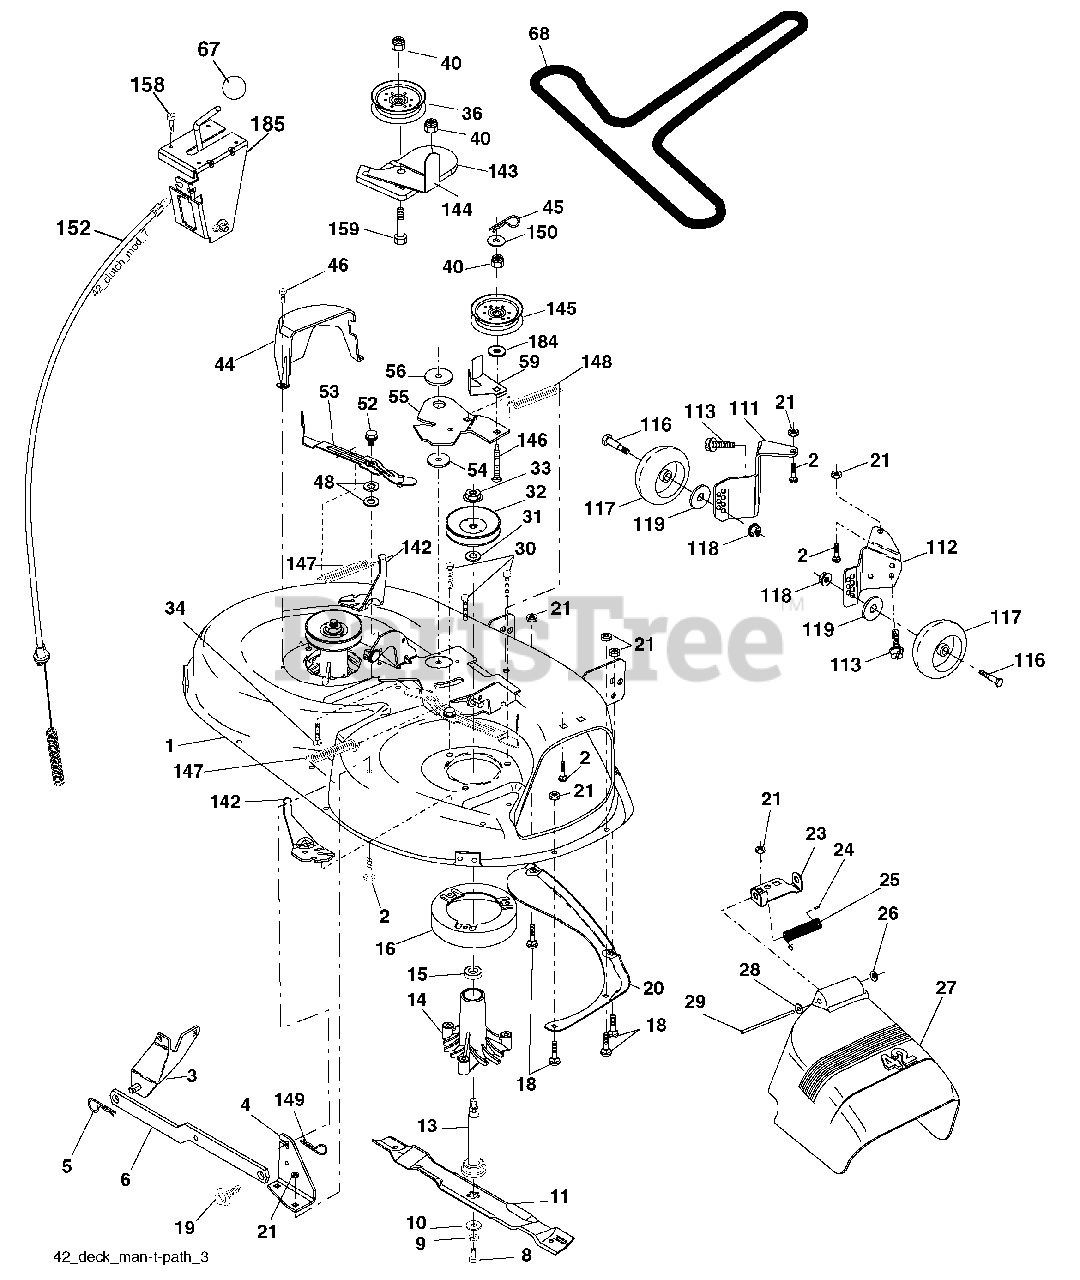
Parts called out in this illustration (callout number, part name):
1	Mower Deck Assembly, 42"
2	Bolt
3	Bracket Asm Fr. Sway Bar 3/42
4	Bracket Asm Deck 42" Sway Bar
5	Retainer Spring
6	Bar Sway Deck
8	Bolt 3/8-24 x 1.25 Gr. 8 patched
9	Washer, Lock
10	Washer, Hardened (The following Blades are available)
11	Blade Mower 42” Hi-Lift (for bagging and discharging)
11	Blade, Mulching 42” Std (for mulching mowers only)
11	Blade Mulching 42” Premium (For better wear when mulching)
13	Shaft As sem bly, Mandrel, Vented
14	Housing, Mandrel, Vented
15	Bearing, Ball, Mandrel
16	Stripper, Mandrel Deck
18	Bolt, Carriage 5/16-18 x 5/8
19	Bolt, Shoulder
20	Baffle, Vortex
21	Nut
23	Bracket, Deflector Mower 42"
24	Cap, Sleeve 80 x 112 Blk Mower
25	Spring, Torsion, Deflector 2 52
26	Nut, Push Phos & Oil
27	Shield, Deflector 42" Blk
28	Washer 11/32 x 5/8 x 16 Ga.
29	Rod, Hinge 42" 6 75 W/G
30	Screw Thdrol
31	Washer, Spacer Mower Vented
32	Pulley, Mandrel
33	Nut, Toplock
34	Bolt Carr SH 3/8-16 x 1-1/2 Gr.5
36	Pulley, Idler, Flat
40	Nut Lock 3/8-16
44	Guard, Mandrel, LH
45	Retainer
46	Screw, Thdrol 1/4-20 x 5/8 T
48	Washer, Hardened
52	Bolt, Shoulder 5/16-18 unc
53	Arm Assembly, Pad, Brake
54	Washer, Hardened
55	Arm, Idler
56	Spacer, Retainer
59	Guard TUV Idler
67	Knob Round
68	V-Belt, 42" Mower
111	Bracket Wheel Gauge LH
112	Bracket Wheel Gauge RH
113	Bolt 5/16-8
116	Bolt Shoulder
117	Wheel Gauge
118	Nut Center Lock 3/8-16
119	Washer 3/8- x 7/8 x 14 Ga.
142	Arm Spring Brake Mower
143	Bracket Arm Idler 42"
144	Keeper Belt 42" Clutch Cable
145	Pulley Idler Flat
146	Bolt Carriage Idler
147	Spring Extension
148	Spring Return Idler
149	Retainer Spring Yellow
150	Washer 9/32 x 3/4 x 10 Ga.
152	Clutch Cable 42"
158	Screw Hex Thd Cut 1/4-20 x 1/2
159	Bolt Rdhd Sqn 3/8-16 unc x 1-3/4
184	Washer 13/32 x 7/8 x 10 Ga.
185	Head Asm Cable Clutch
185	Mandrel Assembly
185	Replacement Mower, Complete
